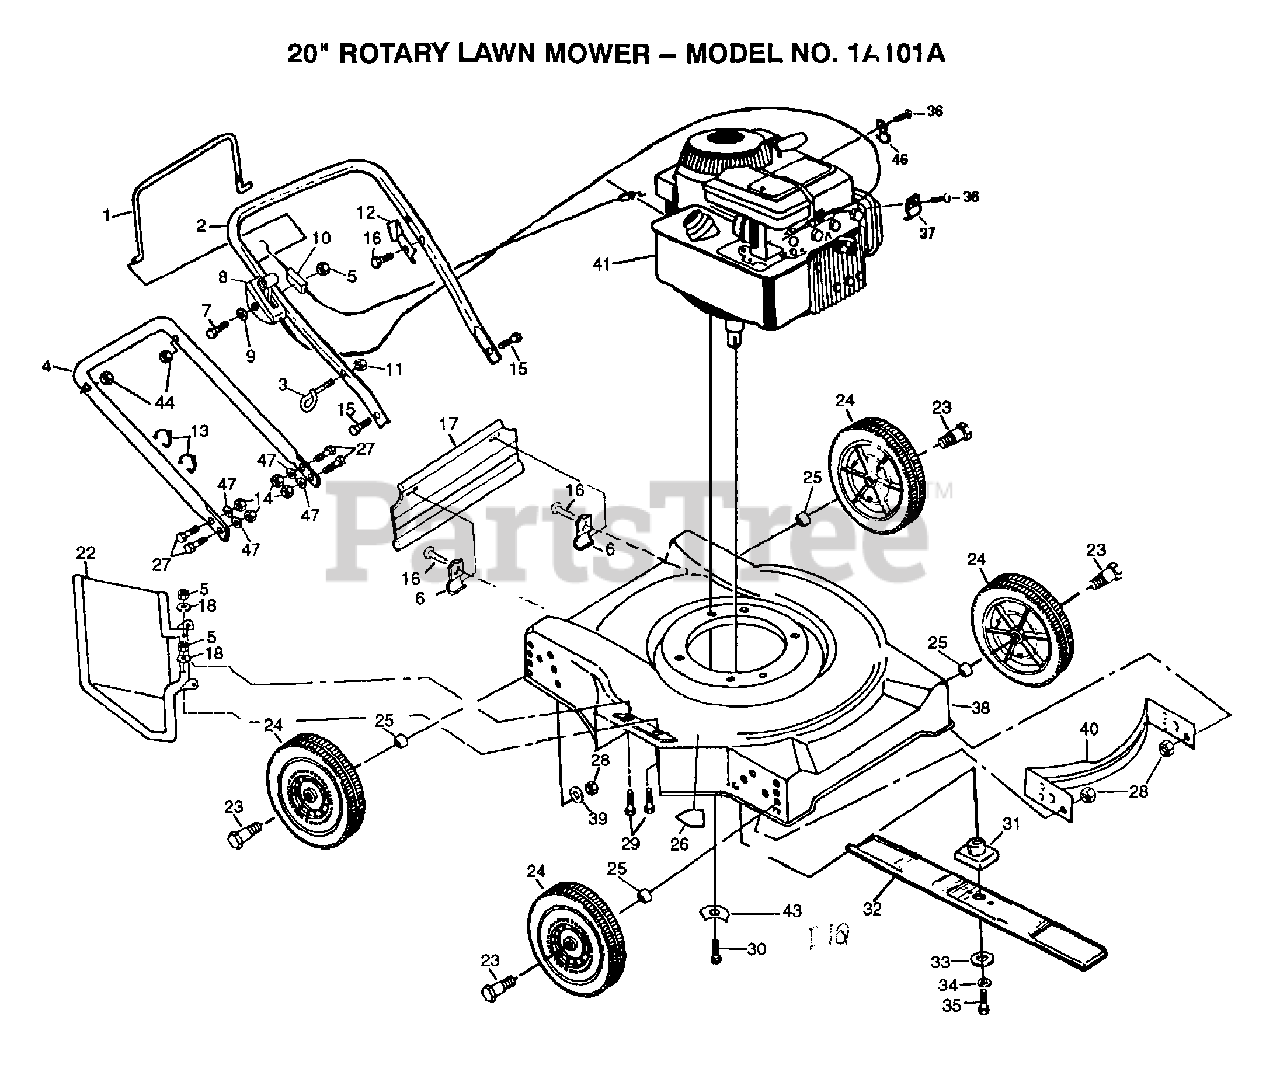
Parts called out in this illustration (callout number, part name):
1	CONTROL BAR PM
2	UPPER HANDLE
3	ROPE GUIDE
4	HANDLE LWR PM
6	"BRKT,DEFL PM"
9	WASHER PM
10	CABLE.CONT.ENG
11	NUT
12	"BRKT,UPSTOP"
14	LOCKNUT
15	BOLT LT
16	TAPPING SCREW
22	"GRD,DISCHARGE"
23	AXLE BOLT
24	WHEEL ASSY
26	DECAL HYT
28	LOCKNUT PM
29	BOLT 1/4-20-1 1/2
30	SCREW
31	BLADE ADAPTOR
32	BLADE.STAND.20INC
33	"WASHER,HARDEN"
34	LOCKWASHER
35	SCREW
36	SCREW PM
37	CABLE CLAMP
46	"CLIP,CABLE"
47	STEEL WASHER
